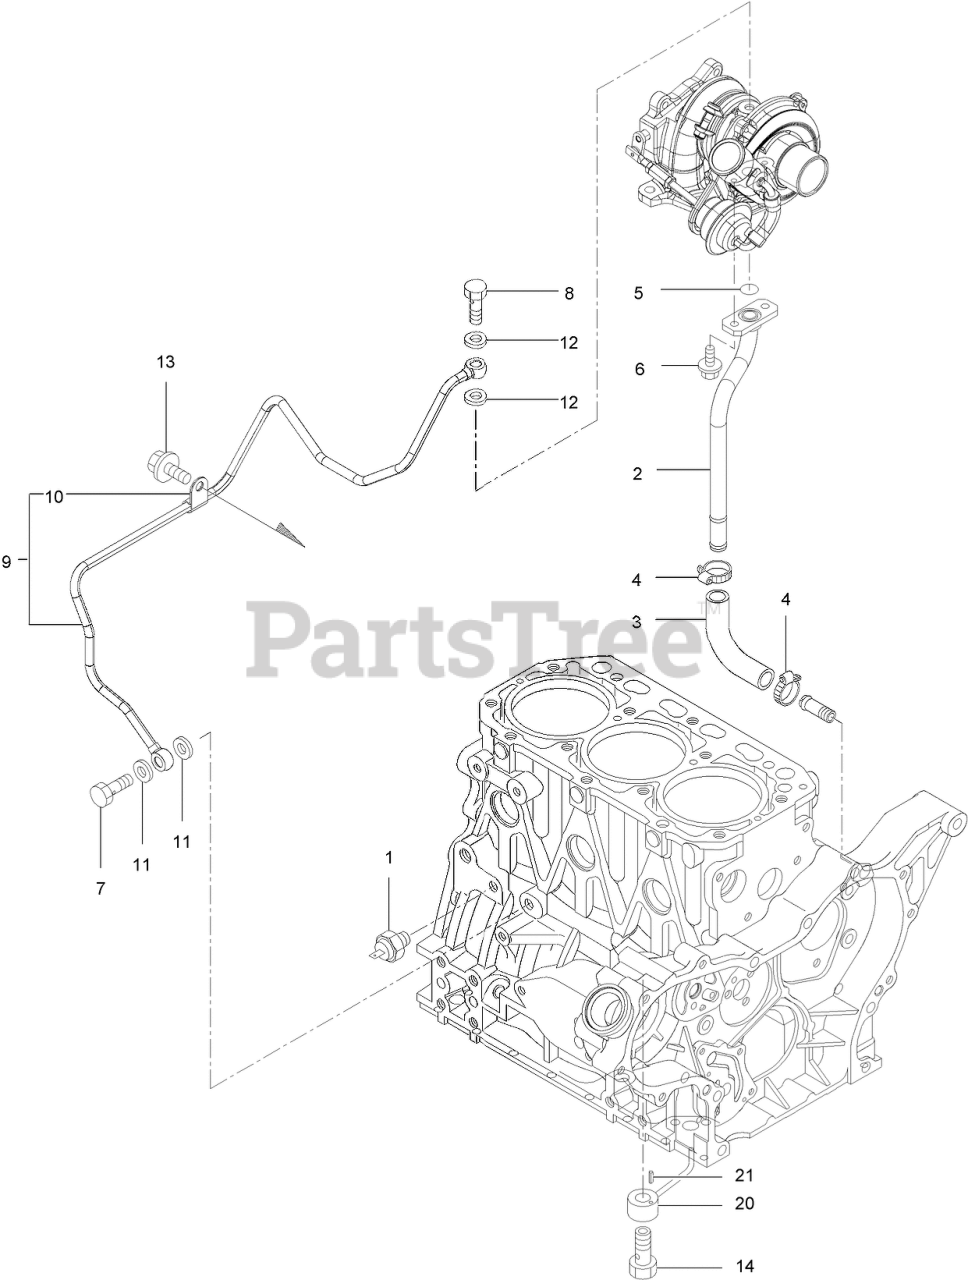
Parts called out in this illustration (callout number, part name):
1	SWITCH-OIL
2	PIPE, OIL RETURN
4	CLAMP-HOSE
7	BOLT-JOINT, PIPE
8	BOLT-JOINT, PIPE
9	LUBE OIL PIPE ASM
10	RETAINER
11	WASHER-SEAL
14	CHECK VALVE ASM
21	PIN-SPRING
